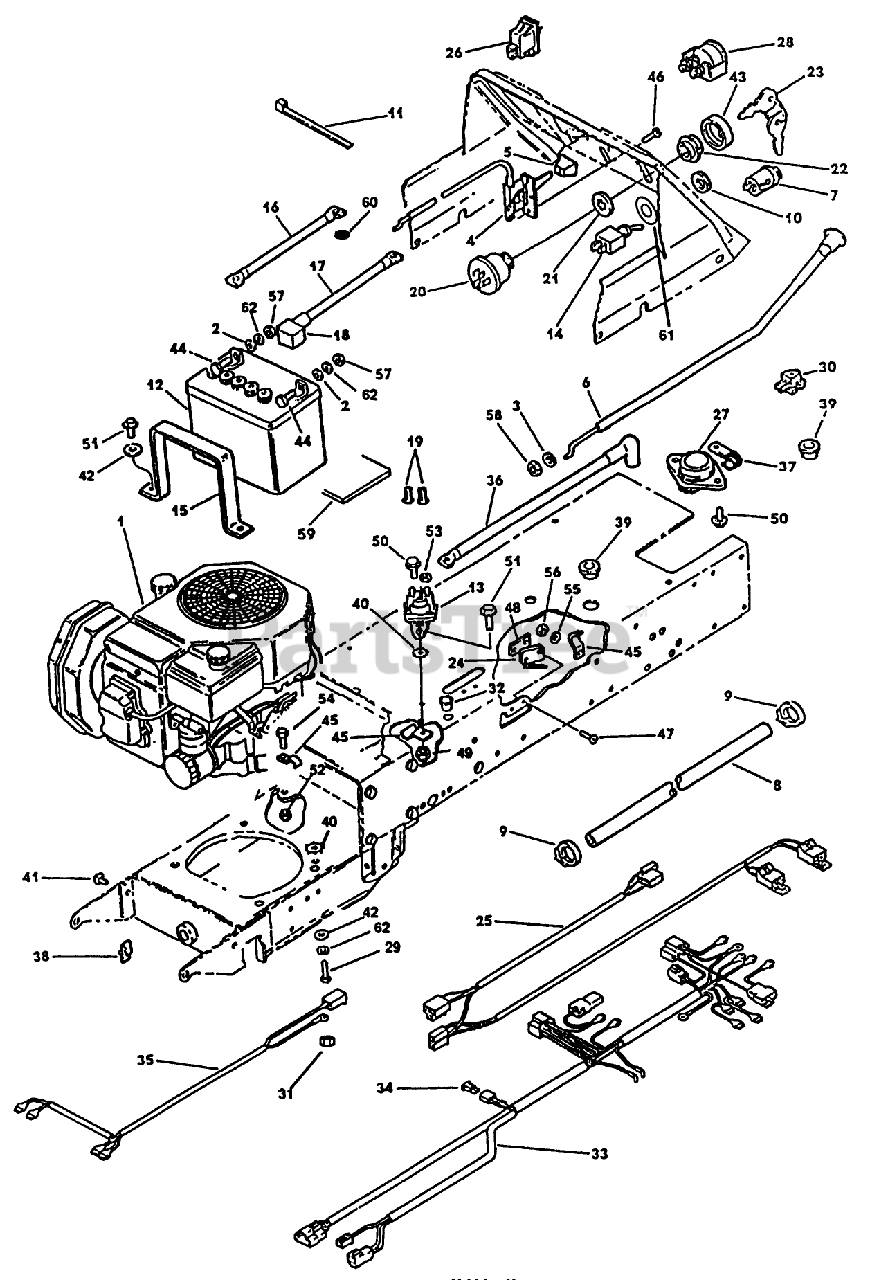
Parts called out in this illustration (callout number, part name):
3	WASHER
5	THROTTLE KNOB
6	CONTROL,CHOKE
7	LIGHT-PTO INDICTOR
13	SOLENOID
14	SWITCH-PTO W/SAFTY
22	NUT
23	KEY
24	SWITCH-SEALED
26	SWITCH ASSEMBLY
27	SWITCH,SEAT
30	SWITCH
31	NUT-LOCK, CONE
38	CLIP
43	BEZEL
44	SCREW - HEX
49	Nut, Hex
52	Nut, Hex
53	NUT-HEX
54	SCREW-HH
56	NUT SS
57	NUT SS
58	NUT-HEX
